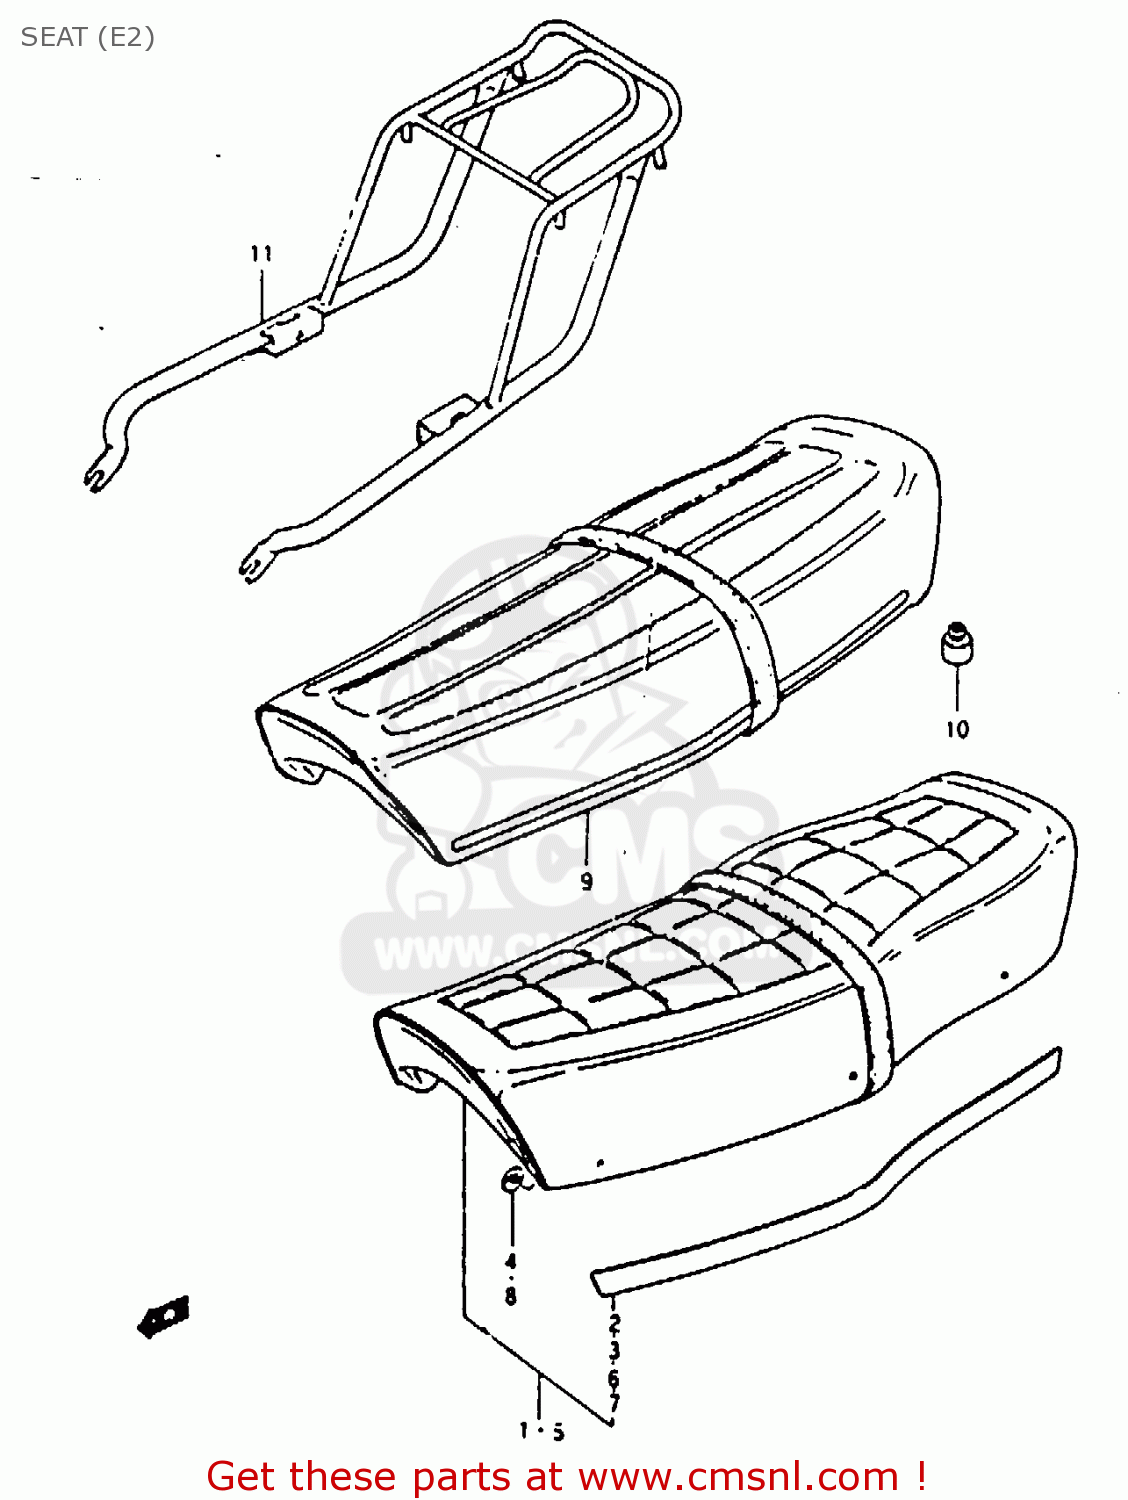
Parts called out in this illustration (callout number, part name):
1	SEAT ASSY
2	MOUL, LH (RED)
3	MOUL, RH (RED)
4	NUT
5	SEAT ASSY
6	MOUL, LH (BLUE)
7	MOUL, RH (BLUE)
8	NUT
9	SEAT ASSY (BLACK)
10	CUSHION
11	CARRIER,SPORT
